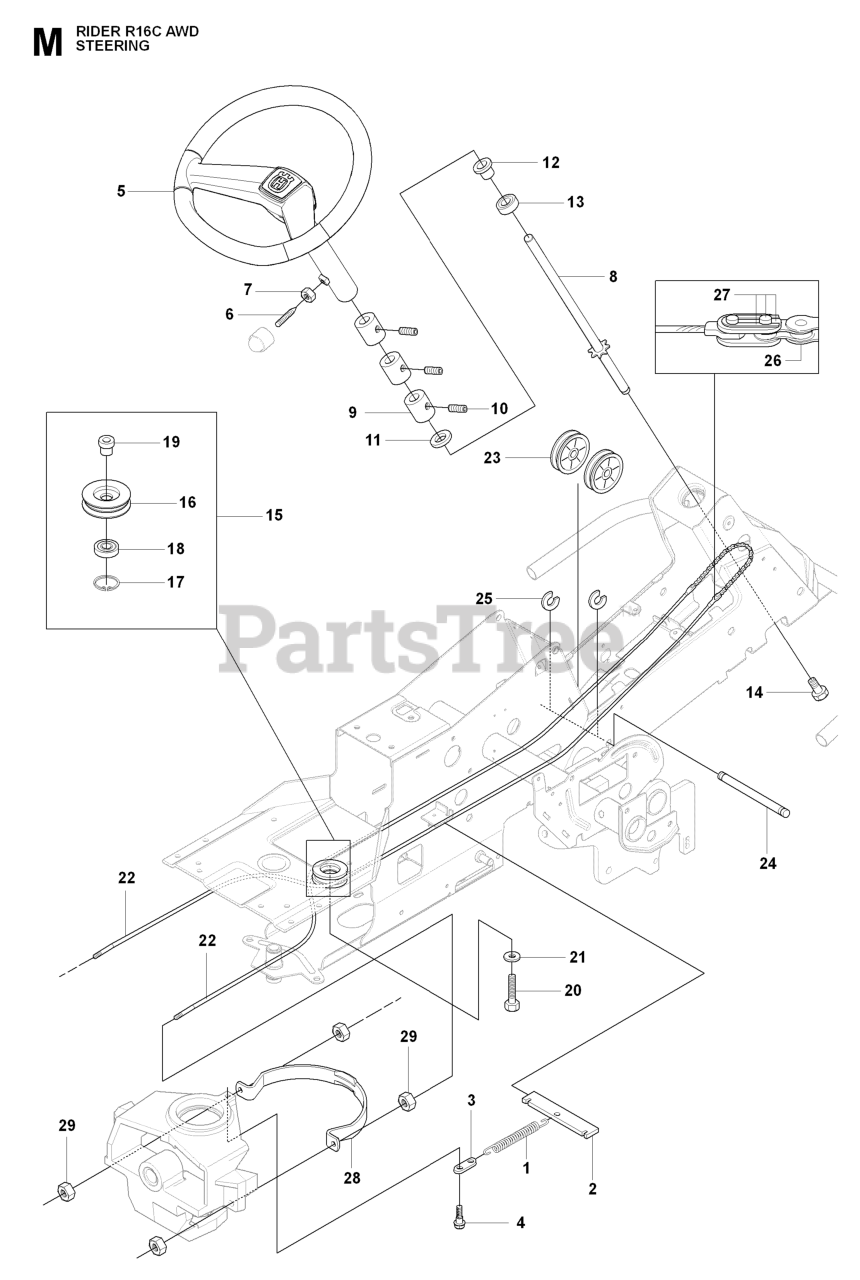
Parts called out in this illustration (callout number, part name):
2	SPRING BRACKET
5	STEERING WHEEL
7	NUT
8	ROD STEERING ASSY
9	SPACER
13	BALL BEARING 6004-2RS1
17	CIRCLIP SGH 47
18	BALL-BEARING 6204-2RS
22	RP STEERING CABLE COMPLETE
25	RETAINING RING
26	STEERING CHAIN
28	WIRE GUIDE
29	NUT
